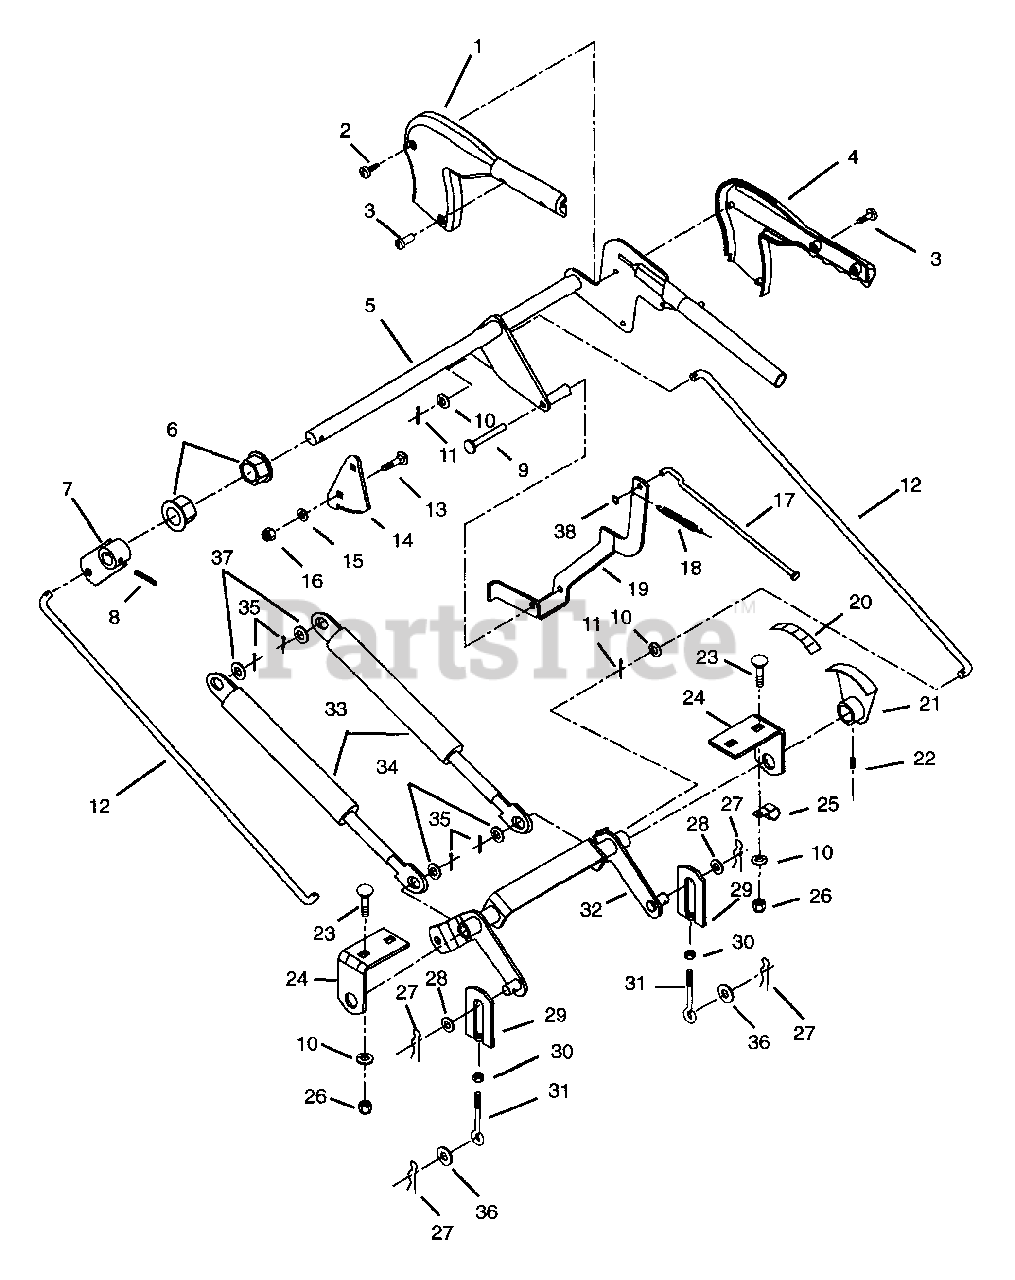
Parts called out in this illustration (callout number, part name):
1	COVER - LIFT RH
2	SCR-TAP 10-16X1.125HI-LOTPHBL
3	POST & SCREW-RAPID ASSY .375
4	COVER - LIFT LH
5	LEVER, LIFT
6	BSHG-FLG .750X.873HEXX.53X1.18
7	ARM, LIFT
8	PIN-GRV .250X1.25 TP A
9	PIN, PIVOT .312 X 2.56
10	WSHR-LK .375X.094 MED PL
11	PIN-COTR .12X1.0 PL
12	LINK, LIFT
13	BLT-RDHDSQNK .31-18X.75
14	QUADRANT, LIFT
15	WSHR-FL-STL .323X.625X.062 PL
16	NUT-LK-NYL.312-18 PL
17	PIN - LIFT
18	SG-TENS .048X.44X2.25 WLD 9
19	LEVER - DETENT
20	DECAL - INDICATOR
21	INDICATOR - DECK HEIGHT
22	SCR-SET .25-20X.25 SKHCUP OH
23	BLT-RDHDSQNK .38-16X.75 SHT PL
24	BRACKET, CENTER LIFT
25	J-CLAMP
26	NUT-HEX .375-16
27	PIN-HAIR EXT .12X.31X2.37 PL
28	WSHR-FL-STL .630X1.005X.062 PL
29	LINK, ADJUSTMENT
30	NUT-JAM .375-16 PL
31	EYE BOLT - .375-16 X 3.00 ZC
32	LEVER, CENTER LIFT
33	SG- GAS COMP .31X.75X10.00
34	WSHR-FL-STL .38X.875X.083 PL
35	PIN-COTR .12X.75 PL
36	WSHR-FL-STL.656X1.312X.095 PL
37	WSHR-FL-STL.406X.812X.065PL
38	RG-RTNG-EXT .250X.010
